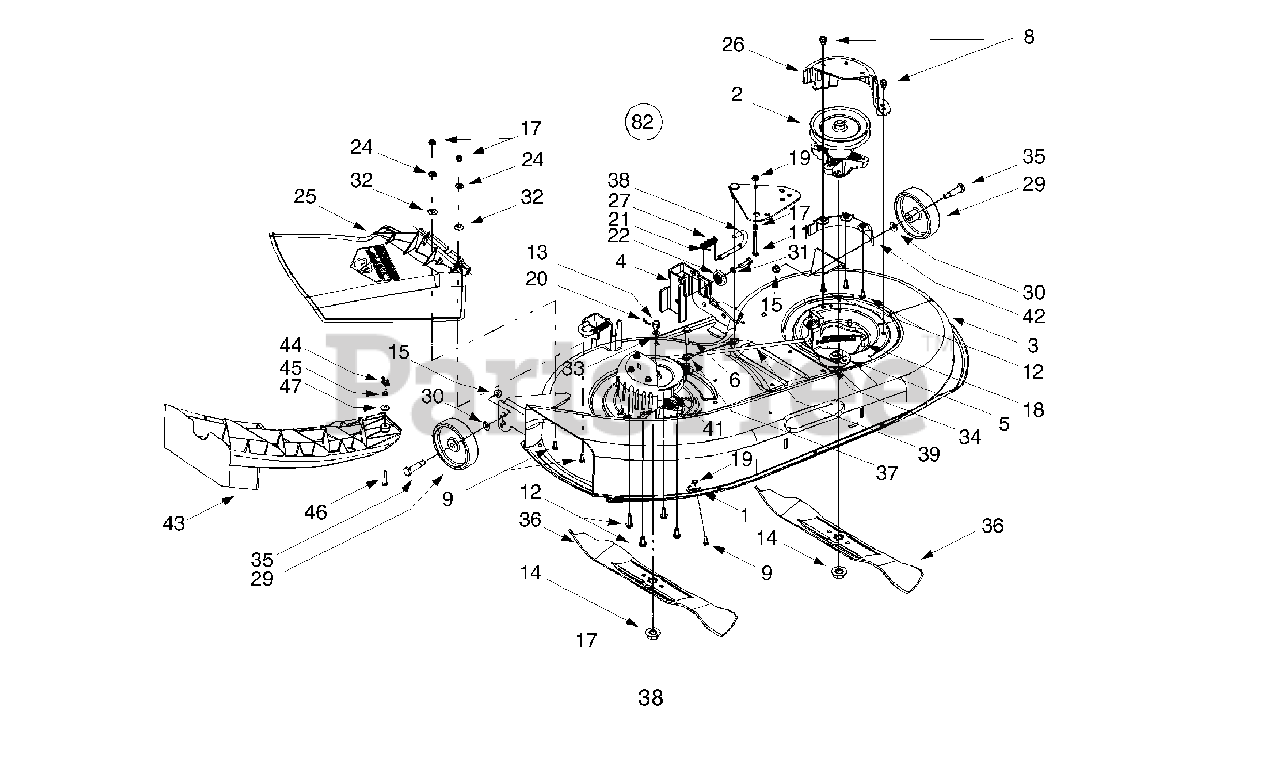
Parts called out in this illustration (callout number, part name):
1	Retainer Hook
2	Spindle Assembly, 5.75 Dia.
6	Hex Cap Screw, 3/8-16 x 1.5
8	Self-tapping Screw, 5/16-18 x .625
9	Hex Cap Screw, 1/4-20 x .62
11	Hex Cap Screw, 1/4-20 x 2.5
12	Self-tapping Screw, 5/16-18 x .75
13	Ferrule, 5/16-18
14	Hex Flange Nut, 5/8-18
15	Flange Lock Nut, 3/8-16
17	Hex Nut, 1/4-20
18	Hex Lock Nut, 5/16-18
19	Hex Flange Lock Nut, 1/4-20
20	Internal Cotter Pin, .072 x 1.12
21	Cotter Pin, 3/32 x 1.0
22	Deck Adjustment Gear
24	Push Nut. .25 x .5
25	Side Discharge Chute Assembly
26	Belt Cover
27	Compression Spring, .406 x .531 x 1.75
29	Deck Wheel, 5 x 1.38
30	Bell Washer, .401 x .87 x .063
31	Lock Washer, 5/16
32	Bell Washer, .265 x .75 x .062
33	Flat Washer, .344 x .688 x .065
34	Flat Washer, .320 x 3.0 x .125
35	Shoulder Screw, .498 x 1.53
36	Three-in-one Blade, Star Center, 21.23"
37	Bracket Cable, 5.35"
38	Deck Release Pin
39	Deck Brake Rod
43	Mulch Plug, 42-inch Decks
44	Wing Nut, 1/4-20
45	Hex Nut, 1/4-20
46	Hex Cap Screw, 1/4-20 x 1.0
47	Flat Washer, .28 x .74 x .063
